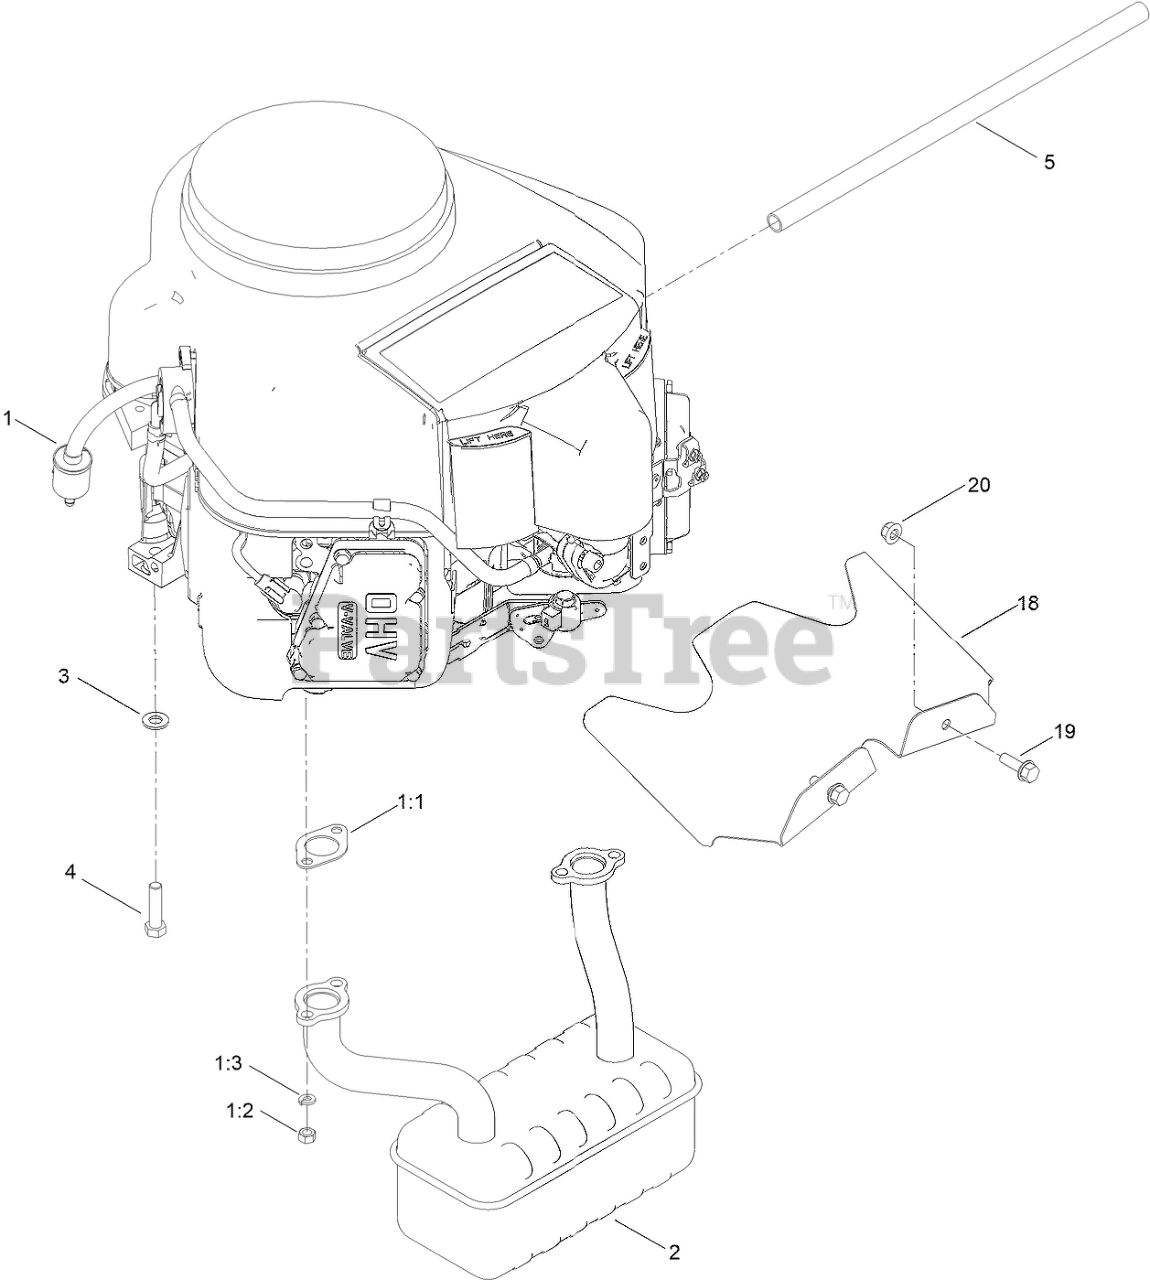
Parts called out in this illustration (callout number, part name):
1:1	GASKET-EXHAUST
1:3	WASHER-LOCK
2	MUFFLER
3	WASHER-FLAT
4	BOLT-HH
5	TUBE-DRAIN, OIL
18	SHIELD-HEAT
19	SCREW-HHF
20	NUT-HF, NI
